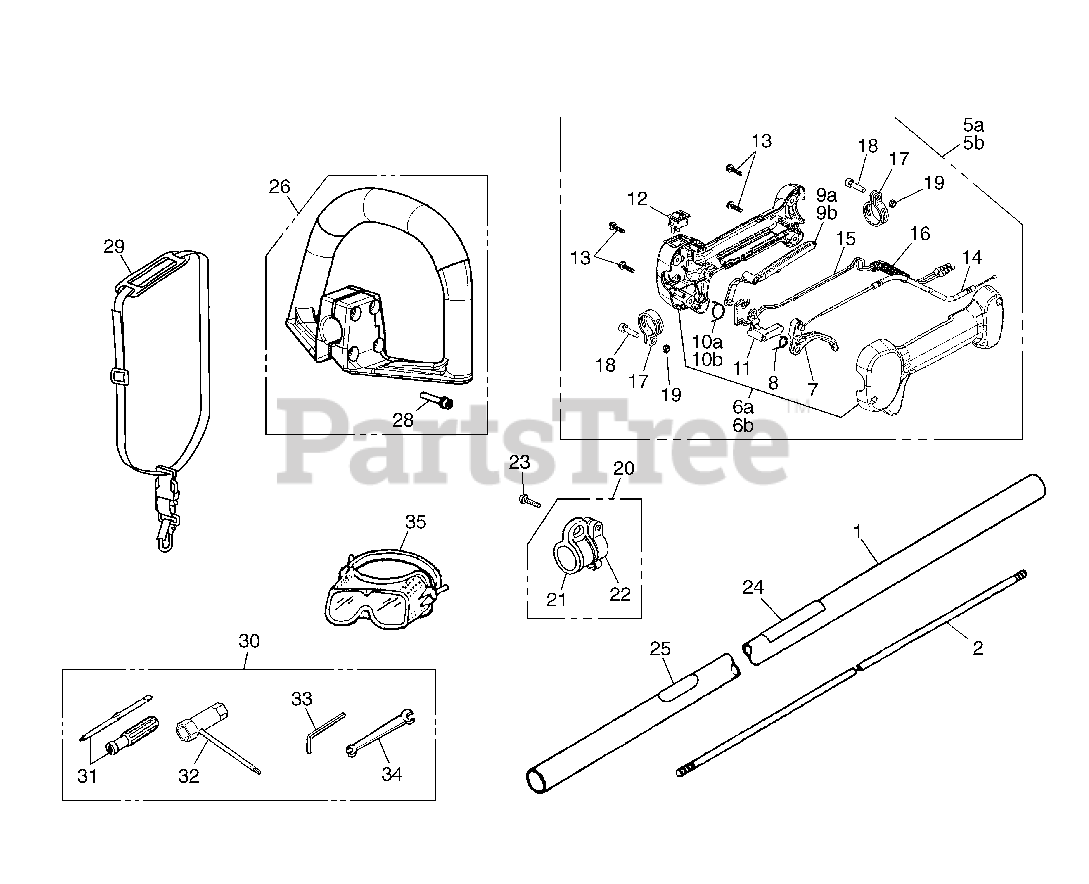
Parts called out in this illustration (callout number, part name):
1	PIPE COMP
5	GRIP ASSY
6	GRIP HALF SET
7	LEVER, THROTTLE
8	SPRING, THROTTLE
9	LEVER FOR GRIP (RPLS -0600)
9	LEVER, SAFETY
10	SPRING JOINT
10	SPRING
11	LEVER JOINT
15	CORD - C
19	NUT
20	HANGER COMP.
21	HANGER
24	NAME PLATE LRTZ2460
25	Caution Label
26	HANDLE ASSY. (RPLS T319514001)
29	STRAP ASSY
30	TOOL-SET
35	GOGGLExxx (RPLS
